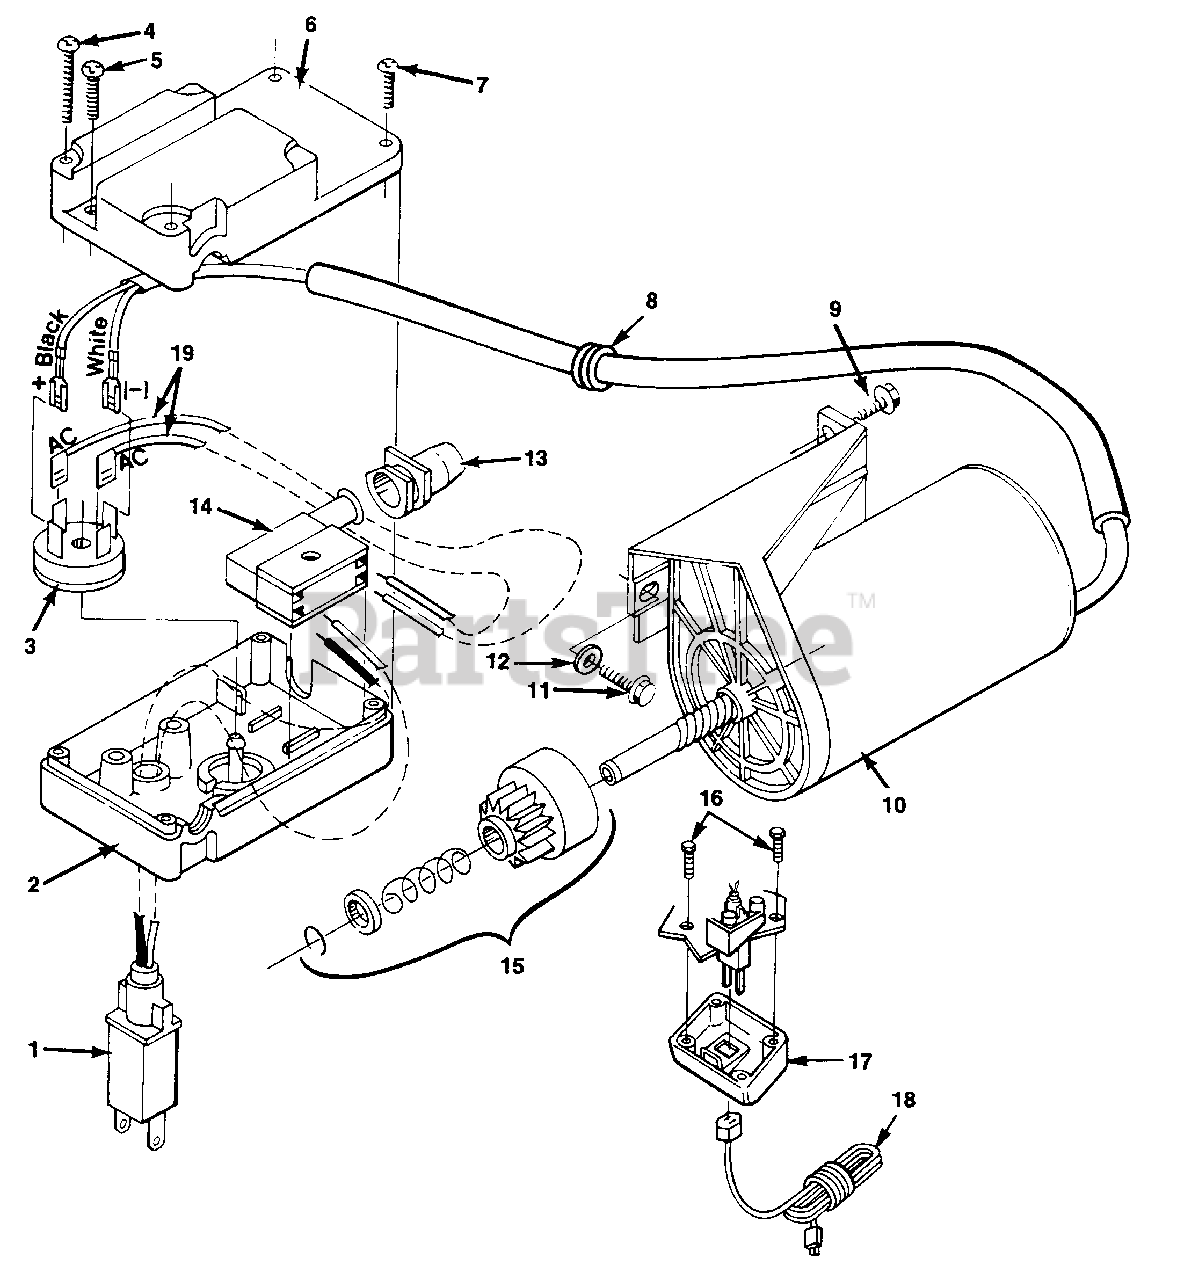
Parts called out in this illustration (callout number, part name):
1	PLUG-Electrical
2	HOUSING-Electrical start
3	RECTIFIER
4	SCREW-Thd. forming #8-16 x 1 1/4
5	SCREW-Thd. forming
6	COVER-Electric start
7	SCREW-Thd. forming #8 x 1/2
8	GROMMET
9	SCREW-Thd. forming
10	MOTOR- Pinion end plate
11	SCREW-Thd. forming 12-24 x 5/8
13	BOOT-Switch
14	SWITCH-Electric starter
15	PINION-
17	COVER-Starter
19	LEAD- Electrical
